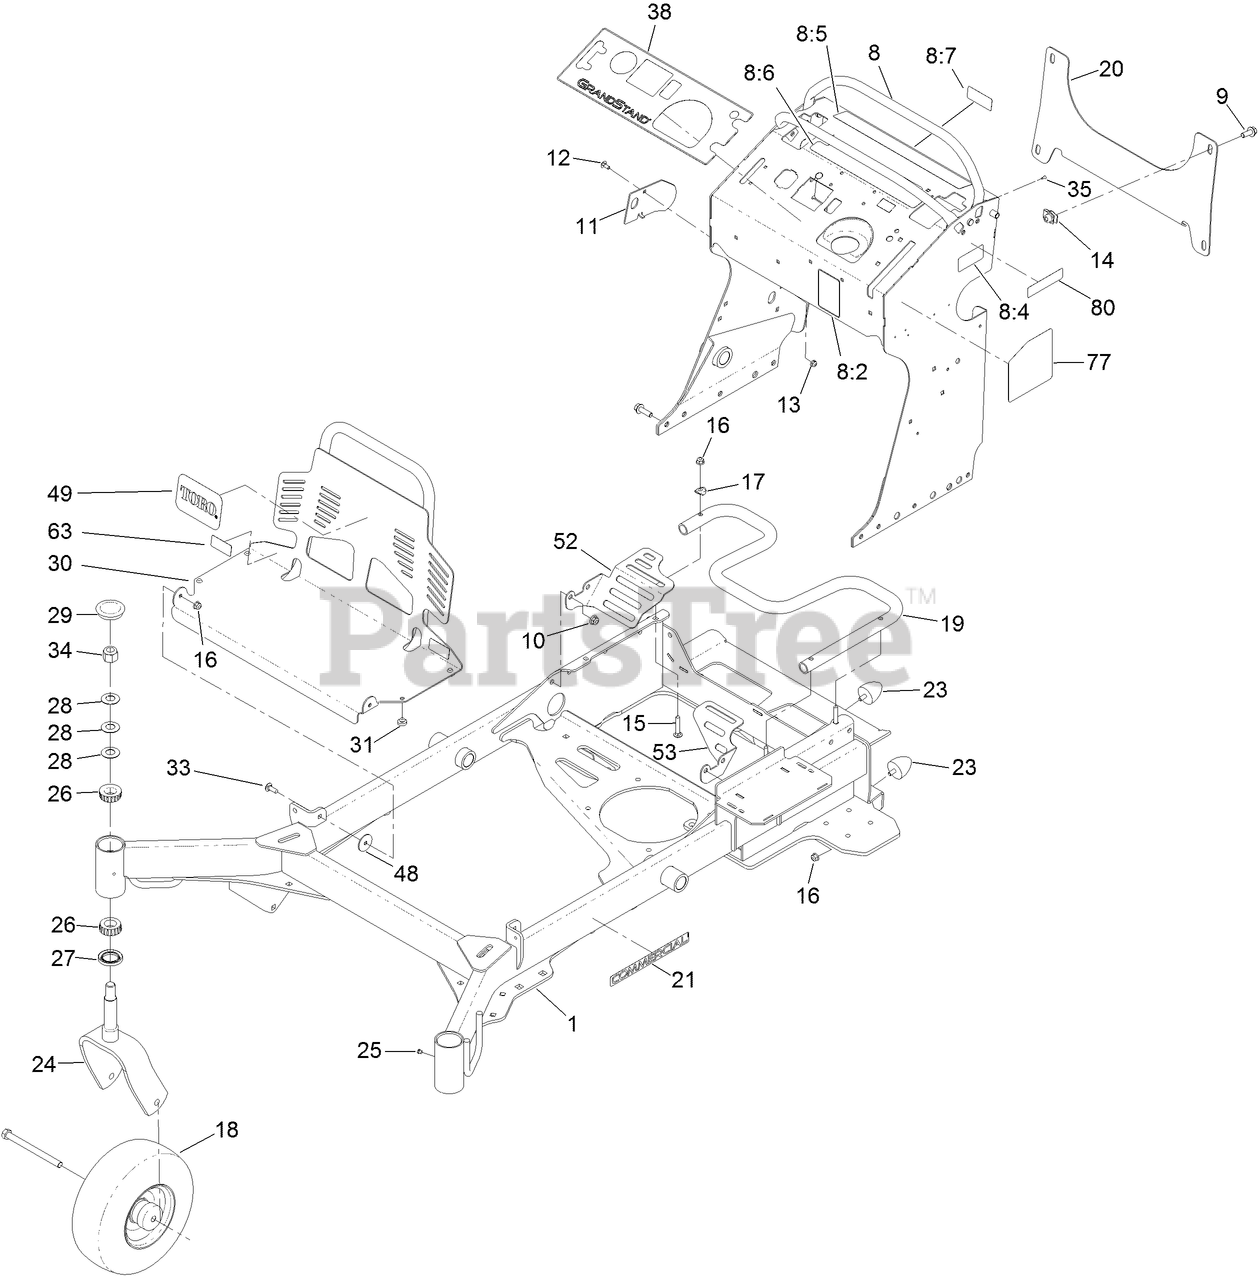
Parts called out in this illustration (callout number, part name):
8	TOWER DECAL ASM
8:2	DECAL-LEVEL, OIL
8:4	DECAL-FILL, FUEL
8:5	DECAL-WARNING
8:6	DECAL-CONTROLS
8:7	DECAL-FUSE
9	SCREW-HHF
10	NUT-HF, NI
11	PLATE-STRIKER
12	SCREW-CARR
13	NUT-HF
14	NUT-TINNERMAN
15	BOLT-CAR
16	NUT-HF, NI
17	WASHER
18	WHEEL/TIRE AND BEARING ASM
19	TUBE-MOUNT, FUEL TANK
20	BRACKET-CROSS
21	DECAL-COMMERCIAL
23	BUMPER-RUBBER
24	FORK-CASTER
26	BEARING-ROLLER, TAPERED
27	SEAL-GREASE
28	WASHER-BELLVILLE
29	CAP-GREASE
30	GUARD-ENGINE
31	BUMPER
33	BOLT-CARR
34	NUT-LOCK, NI
35	RIVET-POP
38	DECAL-PANEL, CONTROL
48	WASHER-NYLON
52	GUARD-FAN, RH
53	GUARD-FAN, LH
63	DECAL-WARNING, NO RIDERS
77	DECAL-SERVICE AID
80	DECAL-ARRESTOR, SPARK
